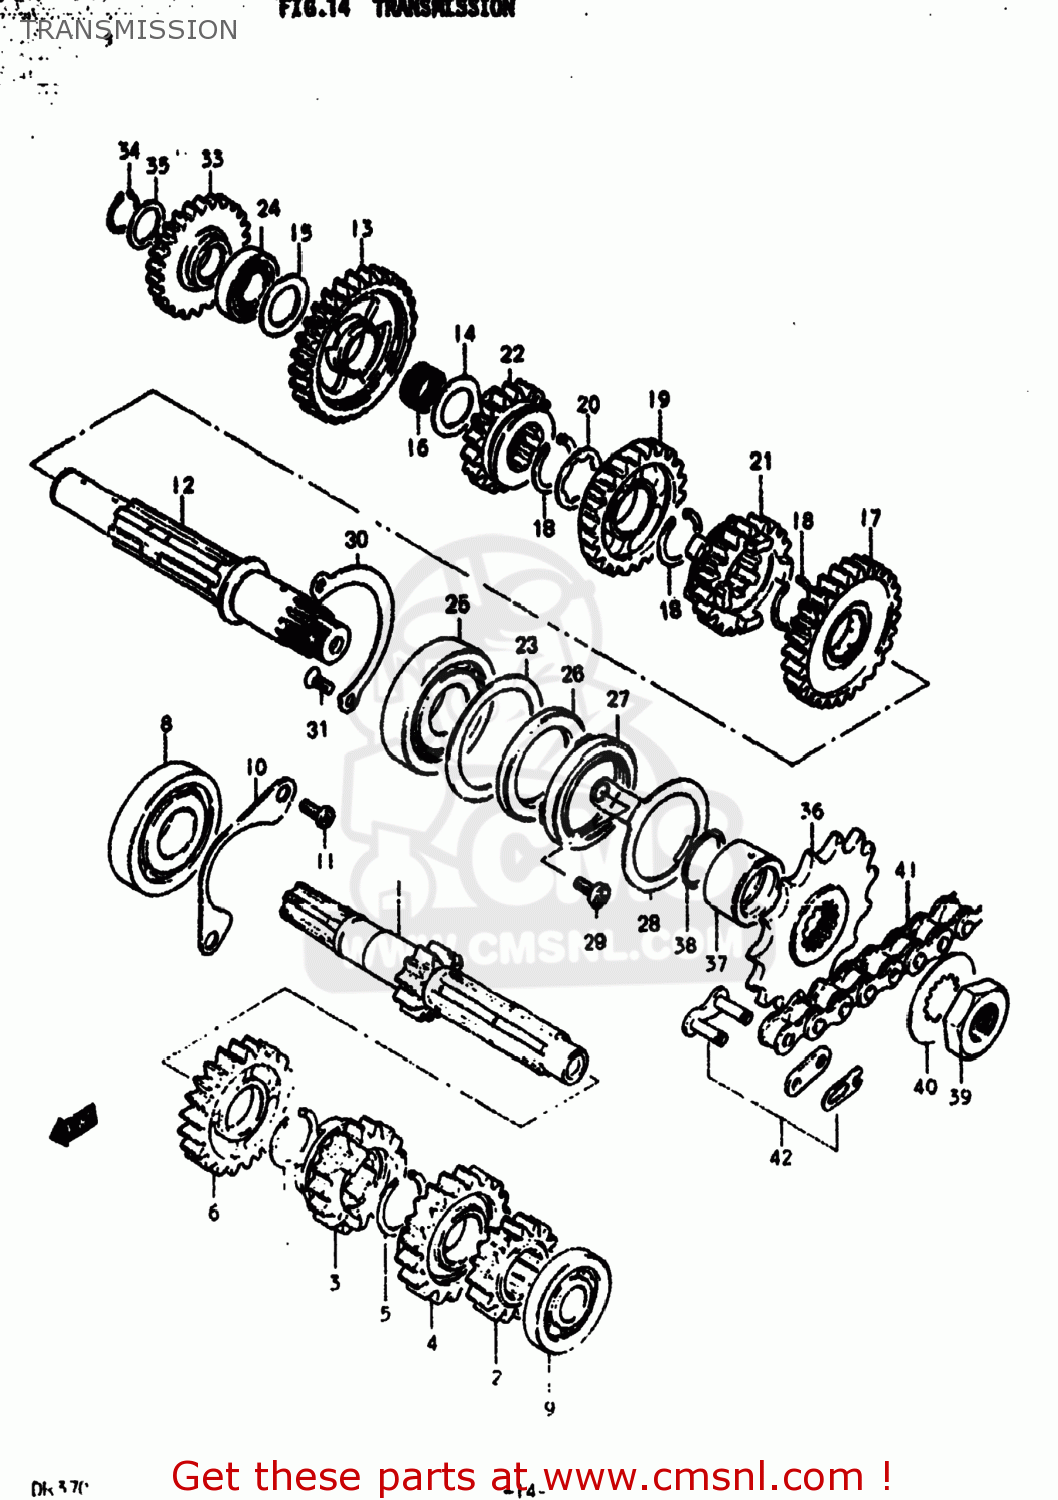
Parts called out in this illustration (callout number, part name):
1	SHAFT,COUNTER
2	GEAR,SECOND DRIVE
3	GEAR,THIRD DRIVE
4	GEAR,FOURTH DRIVE
5	CIRCLIP
6	GEAR,FIFTH DRIVE
7	CIRCLIP
8	BEARING
9	BEARING
10	PLATE,COUNTERSHAFT BEARING
11	SCREW 6X12
12	SHAFT,DRIVE
13	GEAR,1ST DRIVEN(NT:29)
14	WASHER
15	WASHER
16	BEARING(17X21X9.8)
17	GEAR,SECOND DRIVEN
18	CIRCLIP
19	GEAR,THIRD DRIVEN
20	WASHER,LOCK
21	GEAR,FOURTH DRIVEN
22	GEAR,FIFTH DRIVEN
23	WASHER
24	BEARING(17X36X12)
25	BEARING(22X56X16)
26	OIL SEAL (30X47X5)
27	SEAL,OIL(30X47X7)
28	PLATE,DRIVESHAFT OIL
29	SCREW 6X12
30	RETAINER,DRIVE SHAFT BEARING
31	SCREW
33	GEAR,KICK STARTER IDLER(NT:25)
34	CIRCLIP
35	WASHER
36	SPROCKET,ENGINE
37	SPACER,ENGINE SPROCKET
38	O RING(D:2.5,ID:21)
39	NUT
40	WASHER,LOCK
41	CHAIN ASSEMBLY,DRIVE
42	JOINT ASSEMBLY,CHAIN
